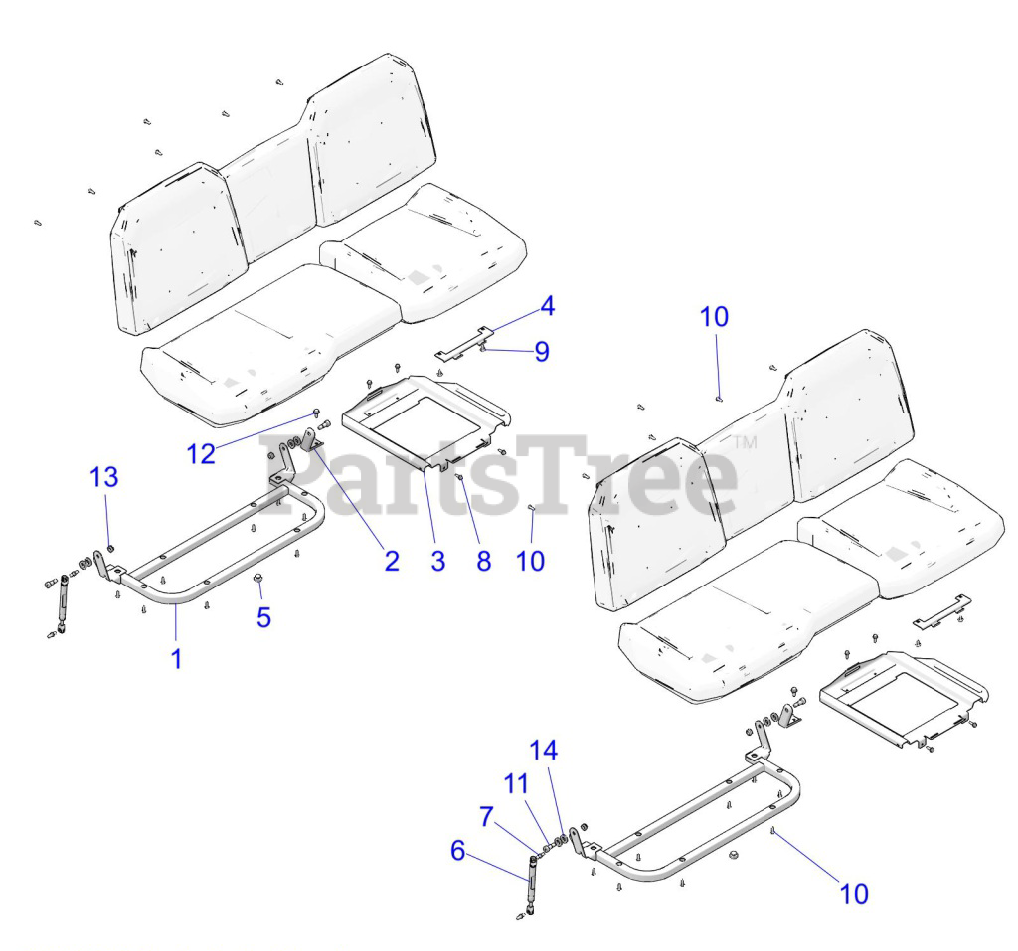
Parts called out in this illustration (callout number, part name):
1	WELD-SEAT BASE-PASS-M.BLK
2	BRKT-SEAT PIVOT-BLK
3	BRKT-SEAT SUPPORT-FIXED-BLK
4	BRKT-SEAT PIVOT-FIXED-BLK
5	BUMPER-RUBBER
6	SHOCK-GAS-285MM
7	BALL-END
8	SCR-M6X1.0X20-HXHD-FLG-TDFM-BL
9	SCR-M6X1X16 TR/TX-M
10	SCR-TX TRUSS-#14X3/4-HI/LO ZBK
11	SCR-SHS-M10X1.5-M12X16 RIE
12	SCR-HWH-M8X1.25X20 TAP/R ZPB
13	NUT-HEX M10X1.5 8 ZOD NYL
14	WASHER-SEATBELT-RUBBER
